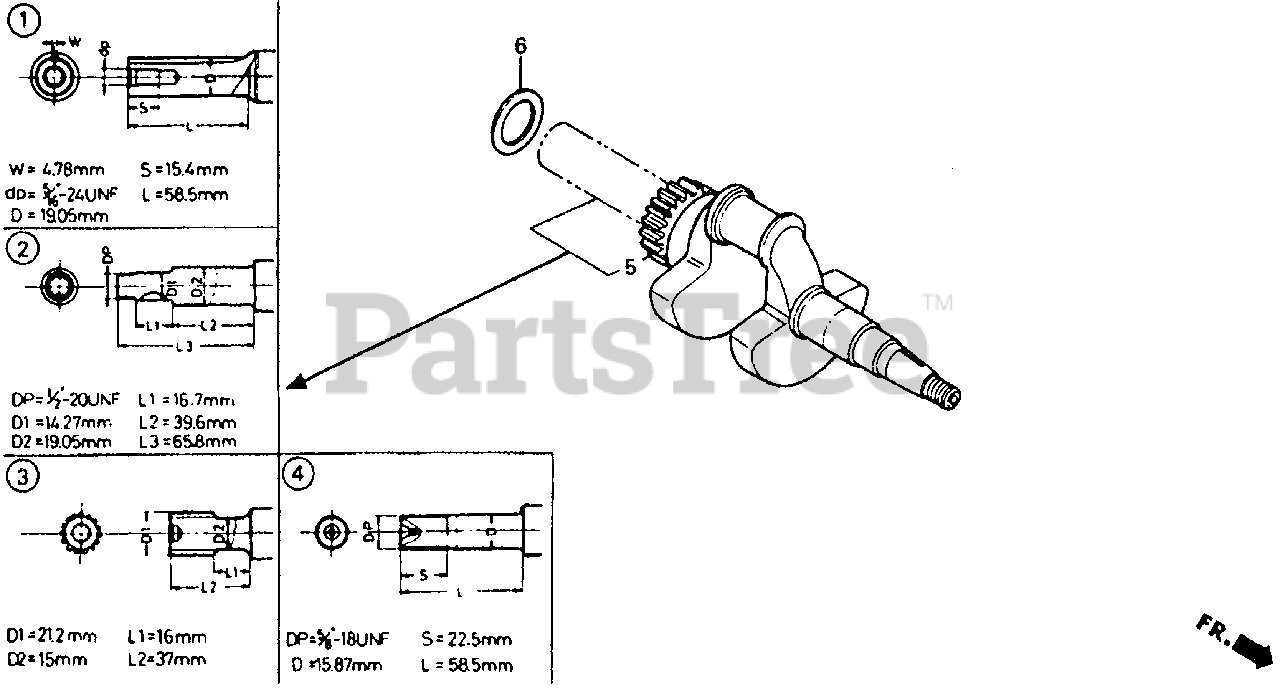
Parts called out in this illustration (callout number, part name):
4	CRANKSHAFT (PE-TYPE)
5	GEAR, TIMING
6	WASHER (25X33X0.1)
